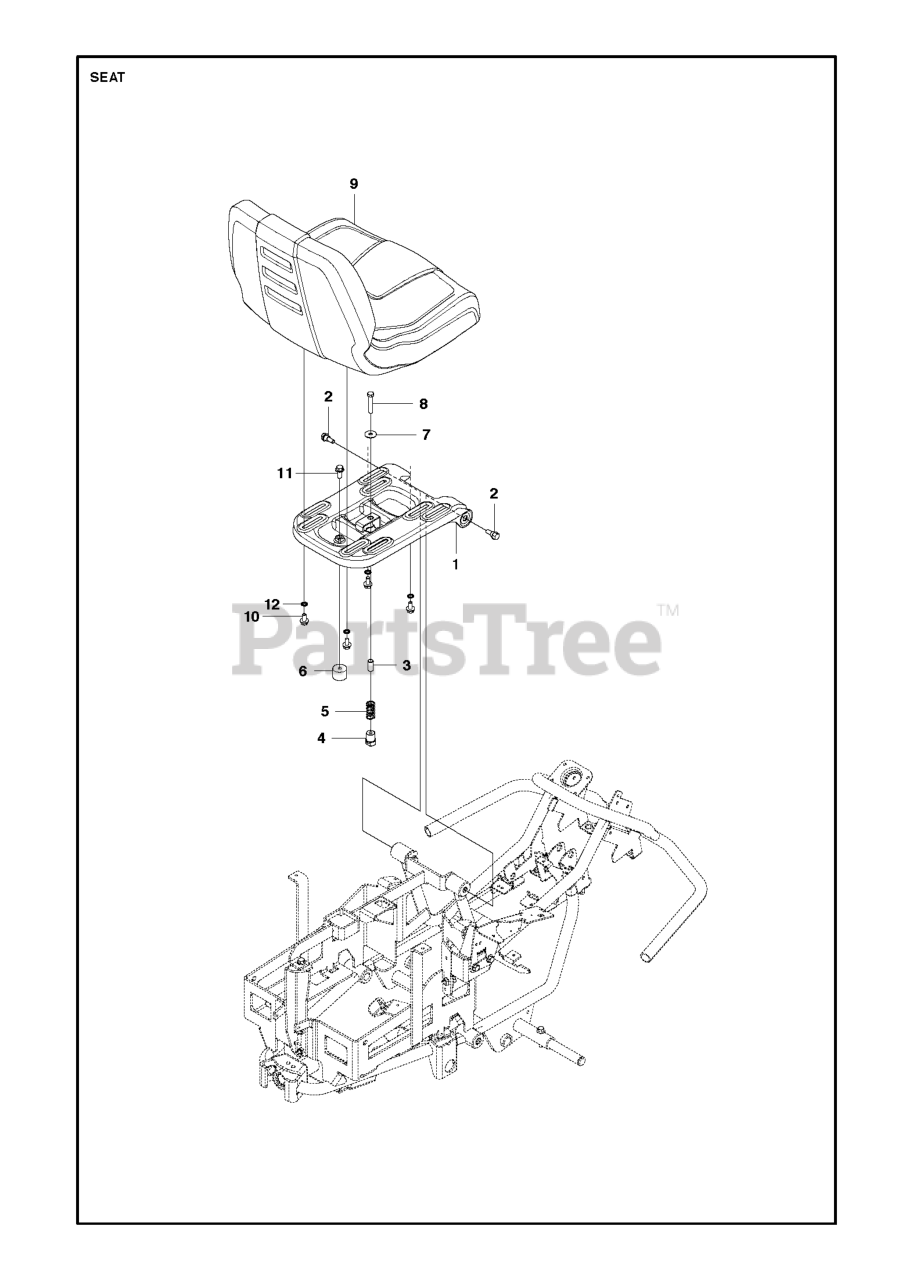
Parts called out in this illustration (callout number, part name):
3	SPACER TUBE
6	ANTIVIBRATION ELEMENT
8	SCREW
